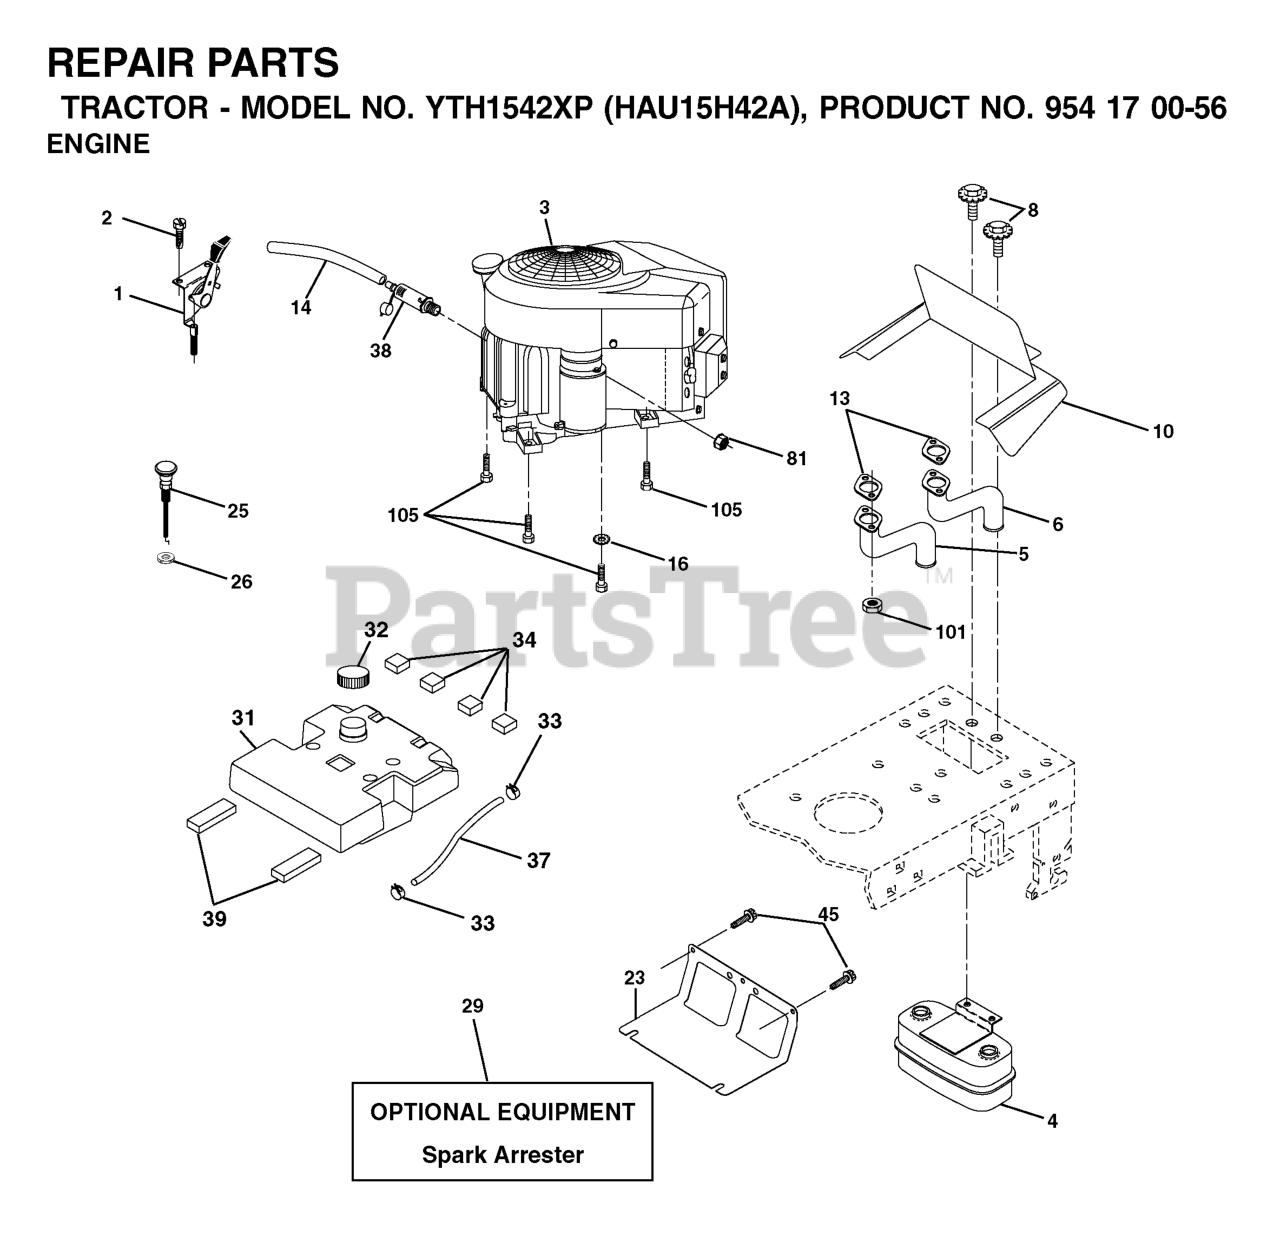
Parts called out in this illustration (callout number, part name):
1	CONTROL, THROTTLE
2	SCREW
4	MUFFLER.TWIN.CYL.LOW.TONE
5	EXHAUST.TUBE.LH.KAWASAKI.
6	EXHAUST.TUBE.RH.KAWASAKI.
8	BOLT.5/16-18UNCX3/4 W/SEMS.BLK
10	RP SHIELD HEAT MUFFLER
13	GASKET.EXHAUST.KAWASAKI.15-1
14	TUBE, DRAIN OIL ASM.
16	LOCKWASHER
23	SHIELD.BROWNING.DBR.GUARD
25	CHOKE CONTROL
26	Nut Keps 3/8 - 24 UNF
29	KIT.SPARK ARRESTOR 794945 B&S
31	TANK.FUEL(3.5.GAL)
32	FUEL CAP
33	HOSE CLAMP
34	PAD-SPACER LT
37	REPL BY 532 00 85-43
39	PAD IDLER TI
45	SCREW, 3/8-16X3/4
81	FLANGE NUT
105	SCREW 3/8-16X1
